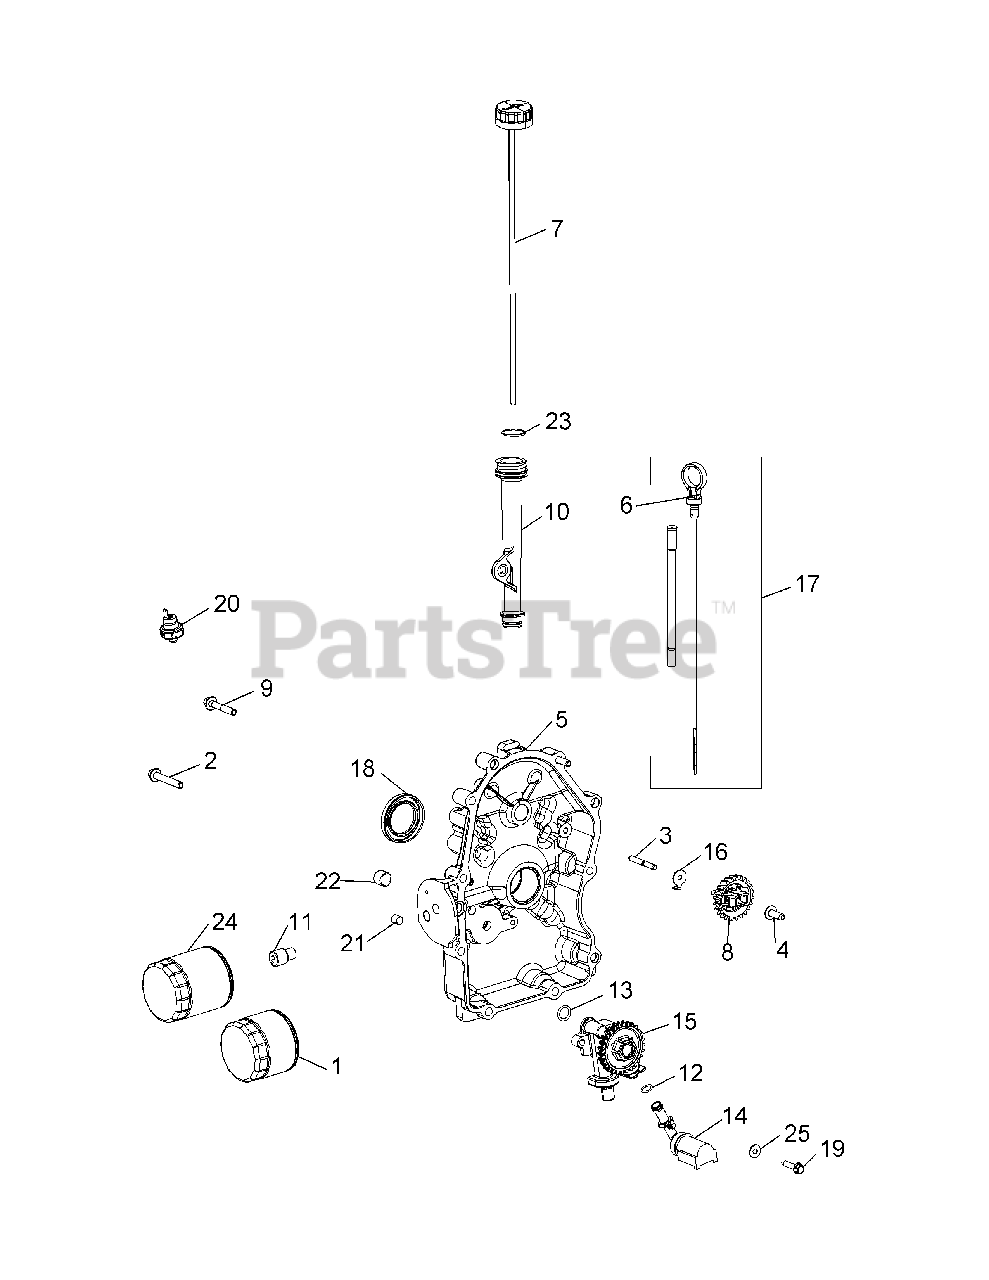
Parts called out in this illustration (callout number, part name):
3	Shaft, Governor Gear
4	Pin, Governor Regulating
5	Closure Plate Assy
8	Kit, Governor Gear w/Pin
9	Screw, Flg M8x1.25x45
11	Nipple, Oil Filter
12	O-Ring, Oil Pick-Up
14	Pick-Up, Oil
15	Kit, Oil Pump Assy
17	Kit, Dipstick/Dipstick Tubes
19	Screw, Thread Forming
20	Switch, Oil Pressure
21	Plug, Ctsk Pipe 1/8"
25	Washer, Flat 1/4" (O.D. 5/8")
